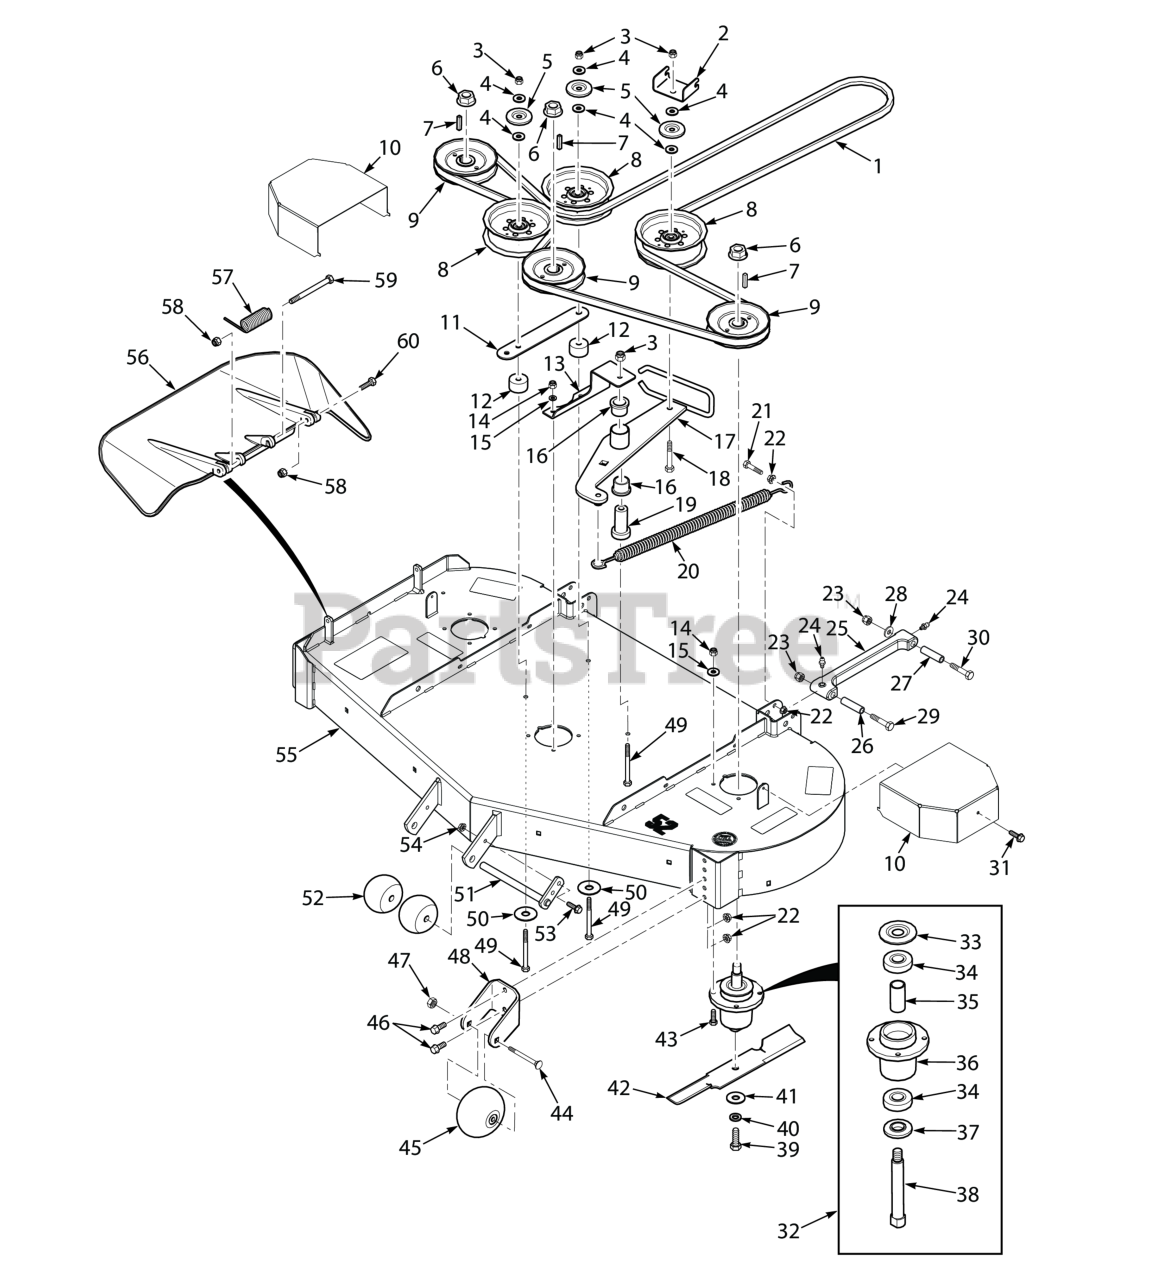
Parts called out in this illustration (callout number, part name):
1	Belt, Cutter Deck - 52
2	Bracket, Belt Guide
3	HEX NUT, ELASTIC STOP LOCK, 3/8-16
4	Flatwasher, 3/8 (.391 x .938 x .105 HD) Grade 8
5	Quick Pin, 5/16" Dia.
6	Nut, 3/4-16 Spriral Lock
7	Key, 1/4 x 1/4 x 1.25" Pulley Mtg.
8	Pulley, 5" Idler
9	Pulley, 5.73" OD - 25mm Bore
10	Belt Cover, SZL
11	Brace, Pulley
12	Spacer, Idler Pulley
13	Support, Idler Pivot - 52
14	Lock Nut, 5/16-18 Elastic Stop Grade 8
15	Lockwasher, 5/16 (.317 x .586 x .078) Helical Spring
16	Bearing, Plastic
17	Idler Arm (incl. item #15)
18	Capscrew, Hex Head 3/8-16 x 2-1/2"
19	Pivot, Idler
20	Spring, Cutter Deck Idler
21	Bolt, Hex Head 3/8-16 x 1-1/2" Grade 8 Black
22	NUT, 3/8-16 SERRATED FLANGE HEX HEAD
23	HEX LOCKNUT, ELASTIC STOP, 1/2-13
24	GREASE FITTING, STR. 1/4-28 SELF TAP.
25	Pusharm Assembly, LH
25	Pusharm Assembly, RH
26	Spacer, Pusharm - Deck
27	Spacer, Pusharm - Axle
28	Flatwasher, 1/2 - .531 x 1.062 x .095
29	Bolt, Hex Head 1/2-13 x 3-1/2"
30	Bolt, Hex Hd. 1/2-13 x 2-1/2" (lower)
31	Screw, 1/4-20 x .375"
32	Spindle Assembly
33	Debris Shield
34	Bearing
35	Spacer, Bearing
36	Spindle Housing Assembly
37	Protector, Bearing
38	Shaft, Spindle
39	Bolt, Hex Head 5/8-11 x 1-1/2"
40	Lockwasher, 5/8" Spring
41	Flatwasher, 5/8-.688 x 1-3/4 x .134 HD
42	Cutter Blade, 18" (52V)
43	Bolt, Hex Head 5/16-18 x 1-1/2" Grade 8
44	Bolt, Hex Head 3/8-16 x 3-1/2"
45	Bolt, Carriage 3/8-16 x 4"
46	Capscrew, 3/8-16 x 1.0" Serrated Flange Hex Hd
47	Bolt, Hex Head 3/8-16 x 1" Ser. Flg.
48	Bracket, Anti-Scalp, (Black)
49	Bolt, Hex Head, 3/8-16 x 3-1/2"
50	Flatwasher, 3/8-.406 x 2.25" x .1875
51	Shaft Weldment, Guide Roller
52	Wheel, Anti-Scalp
53	Bolt, Heax Head 5/16-18 x 1" (48V / 52V)
53	Discharge Chute Assy. SFZ52
54	Nut, Flange Head Elastic Stop 5/16-18
55	Cutter Deck w/Decals
57	Spring, Discharge Chute
58	HEX NUT, ELASTIC STOP LOCK, 5/16-18
59	Bolt, 5/16-18 x 4-3/4" Hex Head
60	Bolt, Hex Head 5/16-18 x 1-1/2" - Front
